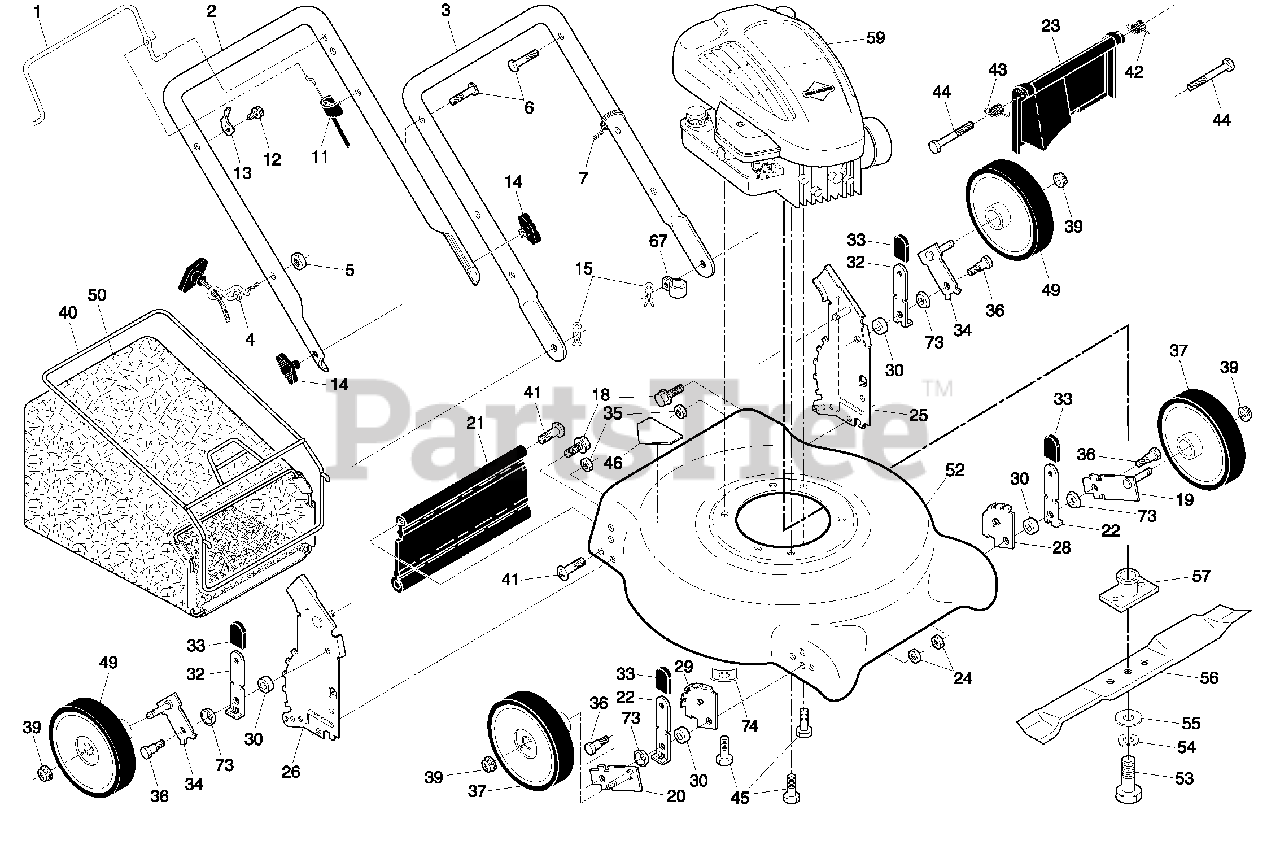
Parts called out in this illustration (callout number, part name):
1	Control Bar
2	Upper Handle
3	Lower Handle
4	Rope Guide
6	Handle Bolt
7	Wire Tie
11	Engine Zone Control Cable
12	Hex Washer Head Screw
13	Up-Stop Bracket
14	Handle Knob
15	Hairpin Cotter
18	Screw 1/4-20 x 3/8
19	Axle Arm Assembly, Front, LH
20	Axle Arm Assembly, Front, RH
21	Rear Skirt
22	Selector Spring, Front
23	Rear Door Assembly
24	Locknut, Hex
25	Handle Bracket Assembly, LH
26	Handle Bracket Assembly, RH
28	Wheel Adjusting Bracket, Front, LH
29	Wheel Adjusting Bracket, Front, RH
30	Spacer
32	Selector Spring, Rear
33	Selector Knob
34	Axle Arm Assembly, Rear
35	Locknut 5/16-18
36	Shoulder Bolt 5/16-18
37	Wheel & Tire Assembly, Front
39	Flanged Locknut
40	Frame, Grass Bag
41	Hinge Screw
42	Spring, Rear Door, LH
43	Spring, Rear Door, RH
44	Bolt, Rear Skirt
45	Hex Head Thread Rolling Screw 3/8-16 x 1
46	Danger Decal
49	Wheel & Tire Assembly, Rear
50	Grass Bag
52	Housing Assembly
53	Hex Head Screw 3/8-24 x 1-3/8 Grade 8
54	Helical Lockwasher
55	Hardened Washer
56	21" Blade
57	Blade Adapter
67	Clip, Cable
73	Washer, Curved
74	Washer, Special, Engine
74	Operator's Manual, English
74	Operator's Manual, Spanish
74	Repair Parts Manual
